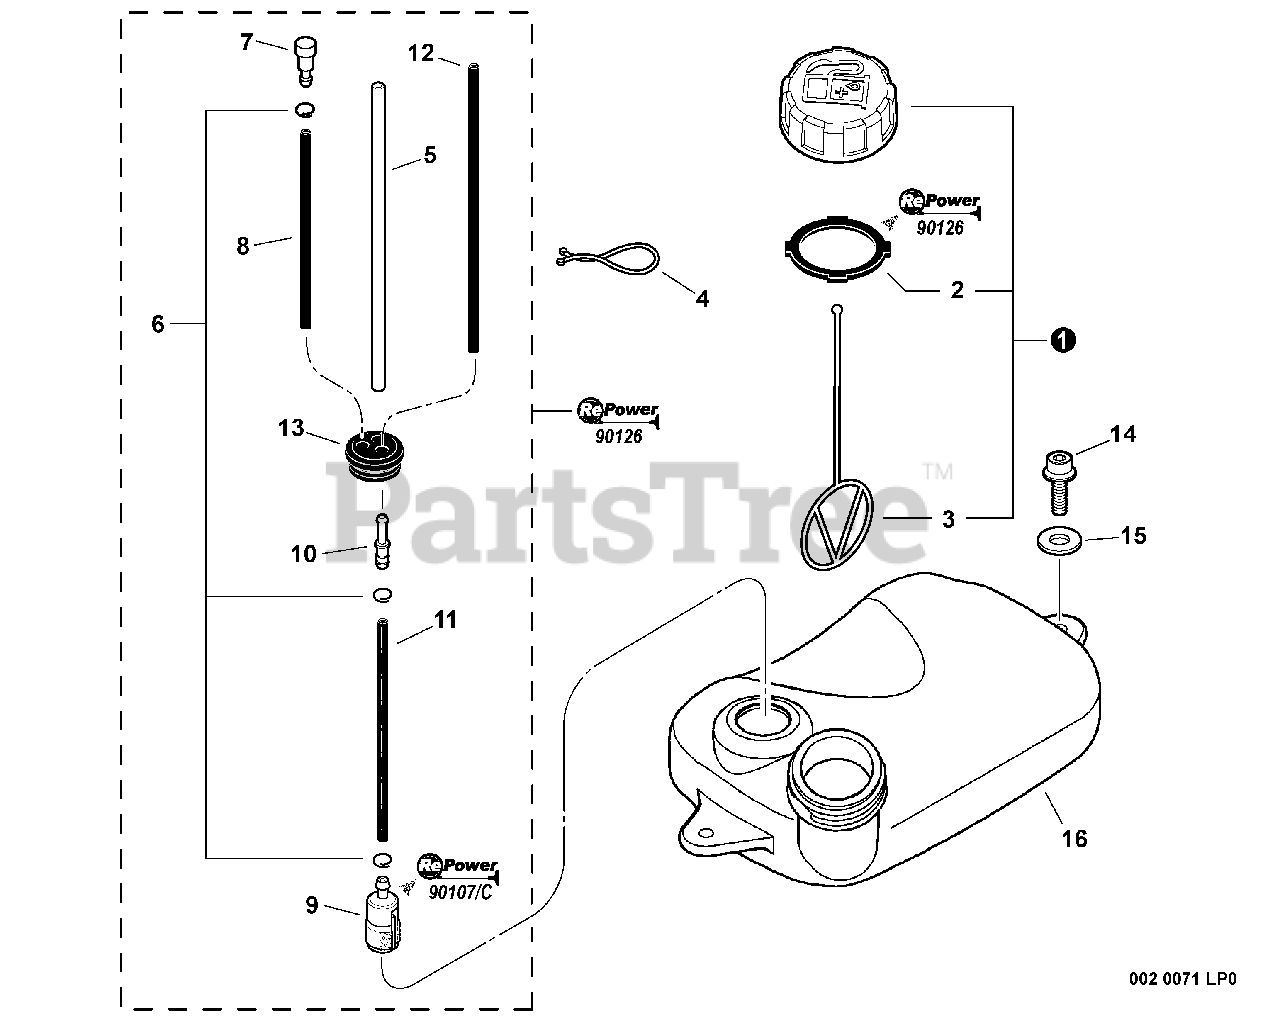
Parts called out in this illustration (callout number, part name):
1	CAP ASSY, FUEL
2	GASKET, FUEL CAP
3	CONNECTOR, CAP L= 100 MM
4	CLIP, TUBE
5	PIPE, FUEL 3×6×125
6	CLIP Ø6
7	VENT ASSY
8	PIPE, FUEL 3x-5x-70 BLACK
9	FILTER, FUEL
10	CONNECTOR, PIPE Ø5ר3.5
11	PIPE, FUEL 3×5×90 BLACK
12	PIPE, FUEL - 3×5×120 - BLACK
13	GROMMET, FUEL
14	BOLT 5×20
15	WASHER 5.5×16×2T
16	TANK, FUEL
17	FUEL SYSTEM KIT
18	TUNE-UP KIT - REPOWER
